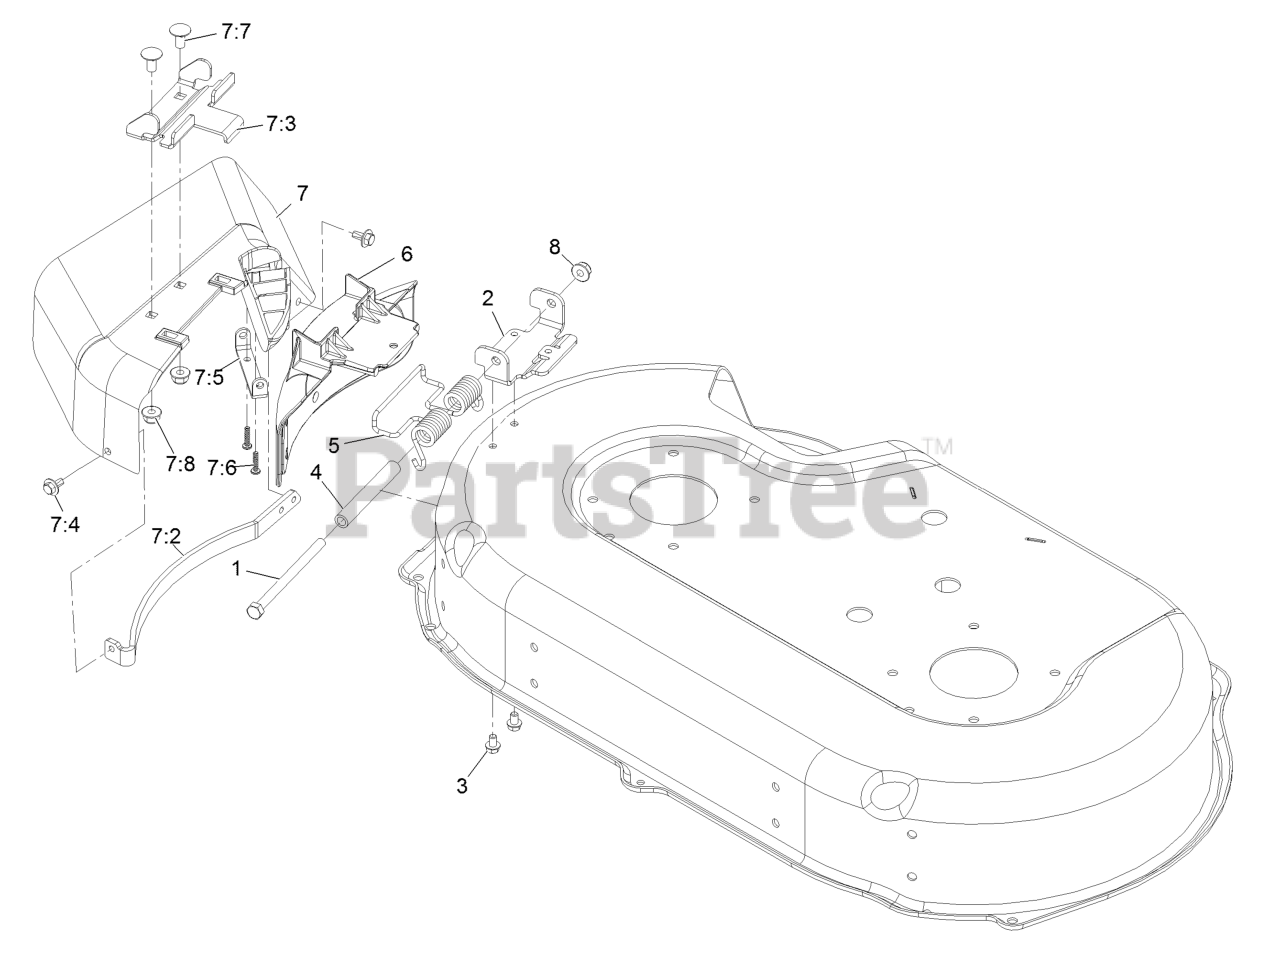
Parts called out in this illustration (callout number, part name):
1	Screw-HH 5/16-18 X 4 1/2
3	Screw-HWH 1/4-20 X 3/8 Taptite
5	Spring-Torsion
6	Cover-Discharge
7	Side Discharge Chute ASM
7:2	Guard-Chute
7:3	Bracket-Chute
7:4	Screw-HHF 1/4-20 X 1/2
7:5	Bracket-Cover
7:6	Screw-PPH
7:7	Bolt-Carriage 5/16-18 X 5/8
7:8	Nut-Nyloc 5/16-18 Flg
8	Nut-Nyloc 5/16-18 Flg
